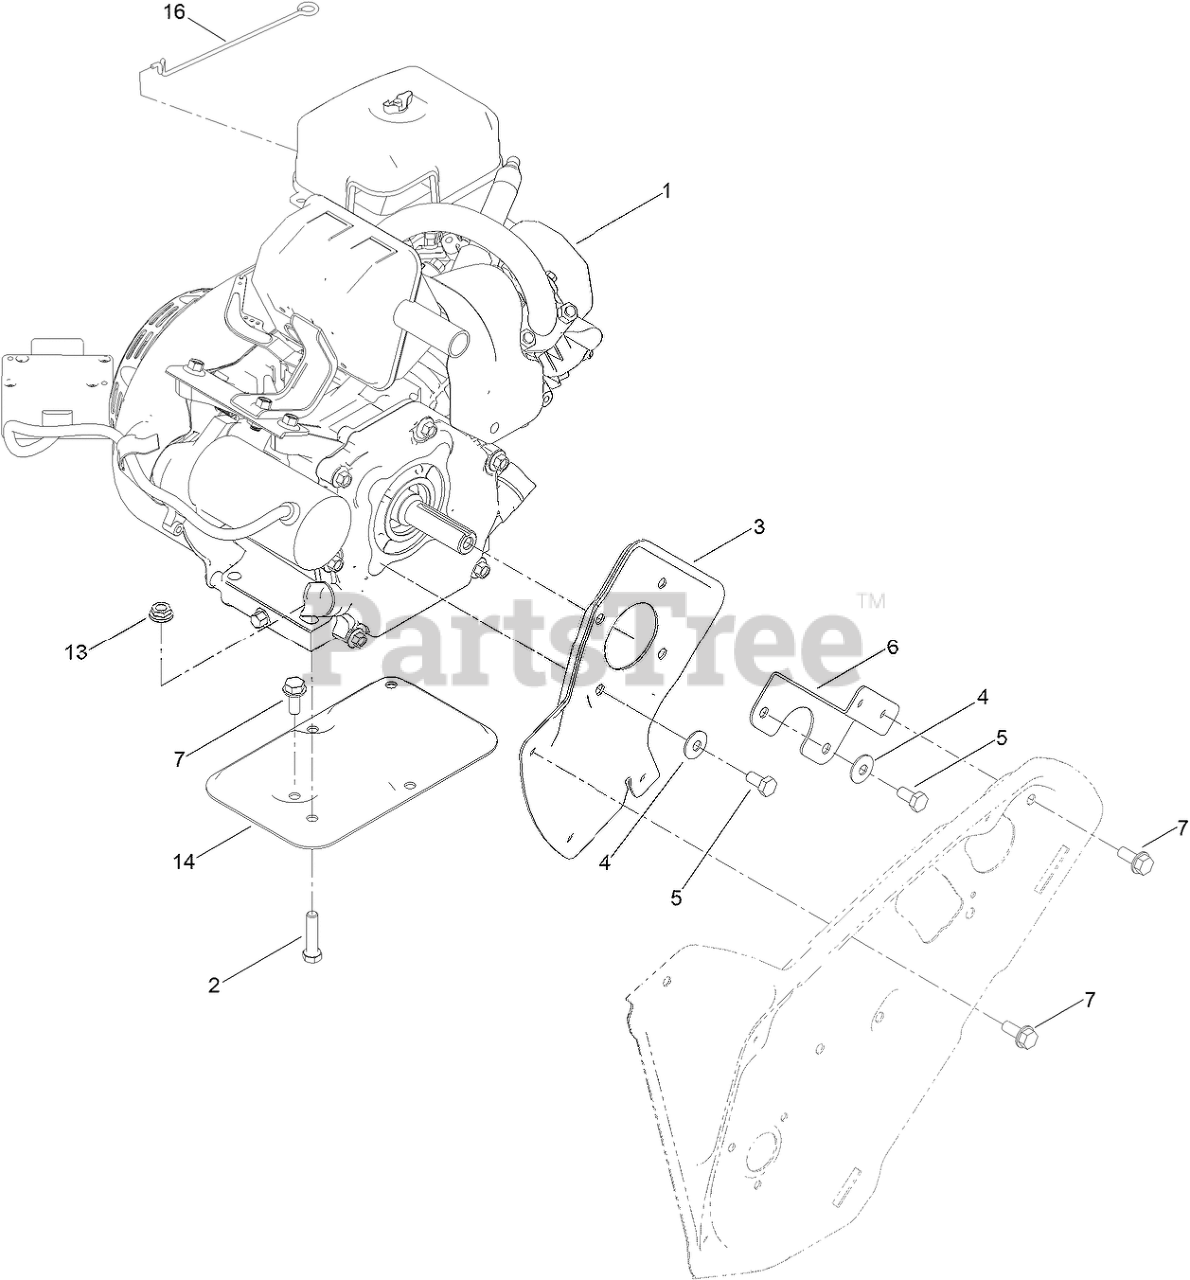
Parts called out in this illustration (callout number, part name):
1	ENGINE-170FS-2
2	SCREW-HH
3	PLATE-ENGINE, PTO
4	WASHER-BELLEVILLE
5	SCREW-HH
6	SUPPORT-ENGINE, SIDE
7	SCREW-HWHTF
13	NUT-HF
14	SUPPORT-ENGINE
16	LINK-CHOKE
